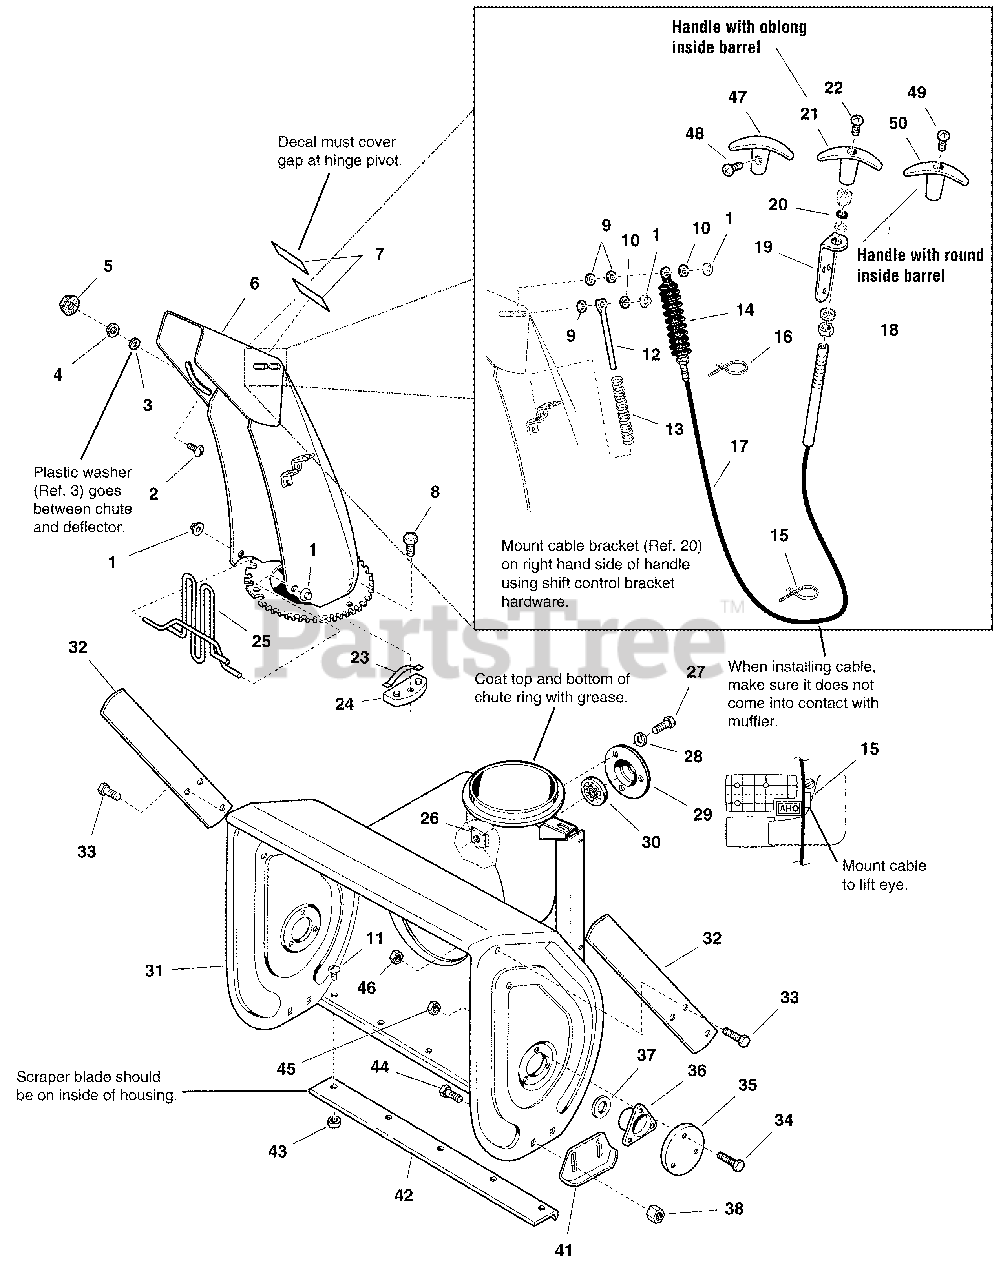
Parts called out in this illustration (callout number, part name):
1	PUSH NUT, 1/4
2	CARRIAGE BOLT, 5/16-18 x 3/4
3	WASHER, Nylon
4	WASHER, Flat, 11/32
5	NUT, Hex ESNA 5/16-18
6	CHUTE & DEFLECTOR ASSEMBLY
7	SEAL, Hinge Decal
8	CAPSCREW, Hex, Washer Head, Plastite 10-14 x 5/8
10	WASHER, Flat
11	CARRIAGE BOLT, Round Head Square Neck 5/16-18 x 5/8
12	ROD, Spring
14	BOOT, Water
15	TIE, Self-Locking
16	TIE, Self-Locking
17	CABLE, Assembly, 67" Long (Includes Ref. Nos. 14, 21, 20 & 22)
18	NUT, 5/16-18
19	BRACKET, Cable
20	SEAL, Rod, Chute Deflector Cable
21	HANDLE, Cable
22	SCREW, Pan Head, #8-32 x 11/16
24	HOLD DOWN, Chute, Black Nylon
25	GUARD & SUPPORT ASSEMBLY, Chute
26	NUT, Retainer, 5/16-18
27	CAPSCREW, Hex Head, 5/16-18 x 17/64
29	RETAINER, Bearing
30	BEARING, Ball
31	HOUSING ASSEMBLY, Auger, 28"
32	CUTTER, Drift
33	CAPSCREW, Hex Head, 5/16-18 x 3/4
34	CAPSCREW, Hex Head, 5/16-18 x 7/8
35	BEARING, Cap
36	BEARING, Auger, Flange
38	NUT, Hex ESNA Flange, 3/8-16
42	BLADE, Scraper, 28"
43	NUT, Hex Flange, 2-Way Lock, 5/16-18
44	CARRIAGE BOLT, 3/8-16 x 3/4
45	NUT, Hex, Center Lock, 5/16-18
46	NUT, Hex KEPS Conical Washer, 5/16-18
48	SCREW, Set, Hex #10-24 x 3/8
49	HANDLE "T"
50	SCREW, Round Head
